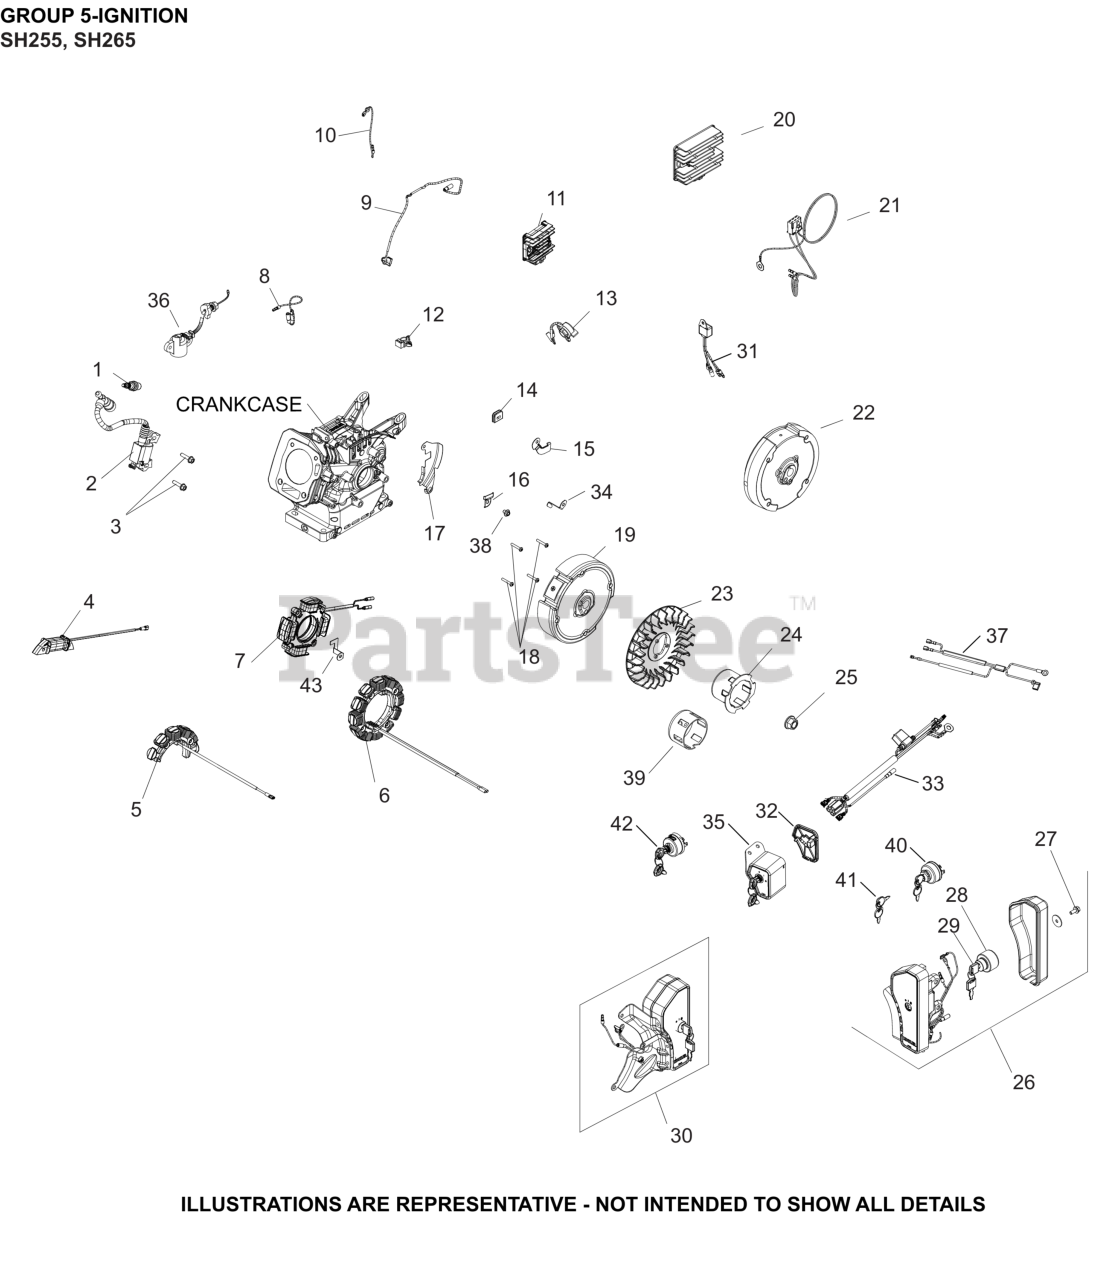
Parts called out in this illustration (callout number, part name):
1	SPARK PLUG
2	MODULE, IGNITION
3	SCREW, M6 X 25-(#25086436S)
9	LEAD, GROUND TO KILL
12	CLIP, WIRE HARNESS
13	SWITCH, IGNITION
19	FLYWHEEL ASSEMBLY
23	FAN, FLYWHEEL
25	NUT, FLYWHEEL (W/SERRATIONS)
30	CLIP, WIRE HARNESS-DISCONTINUED
39	STARTER CUP
